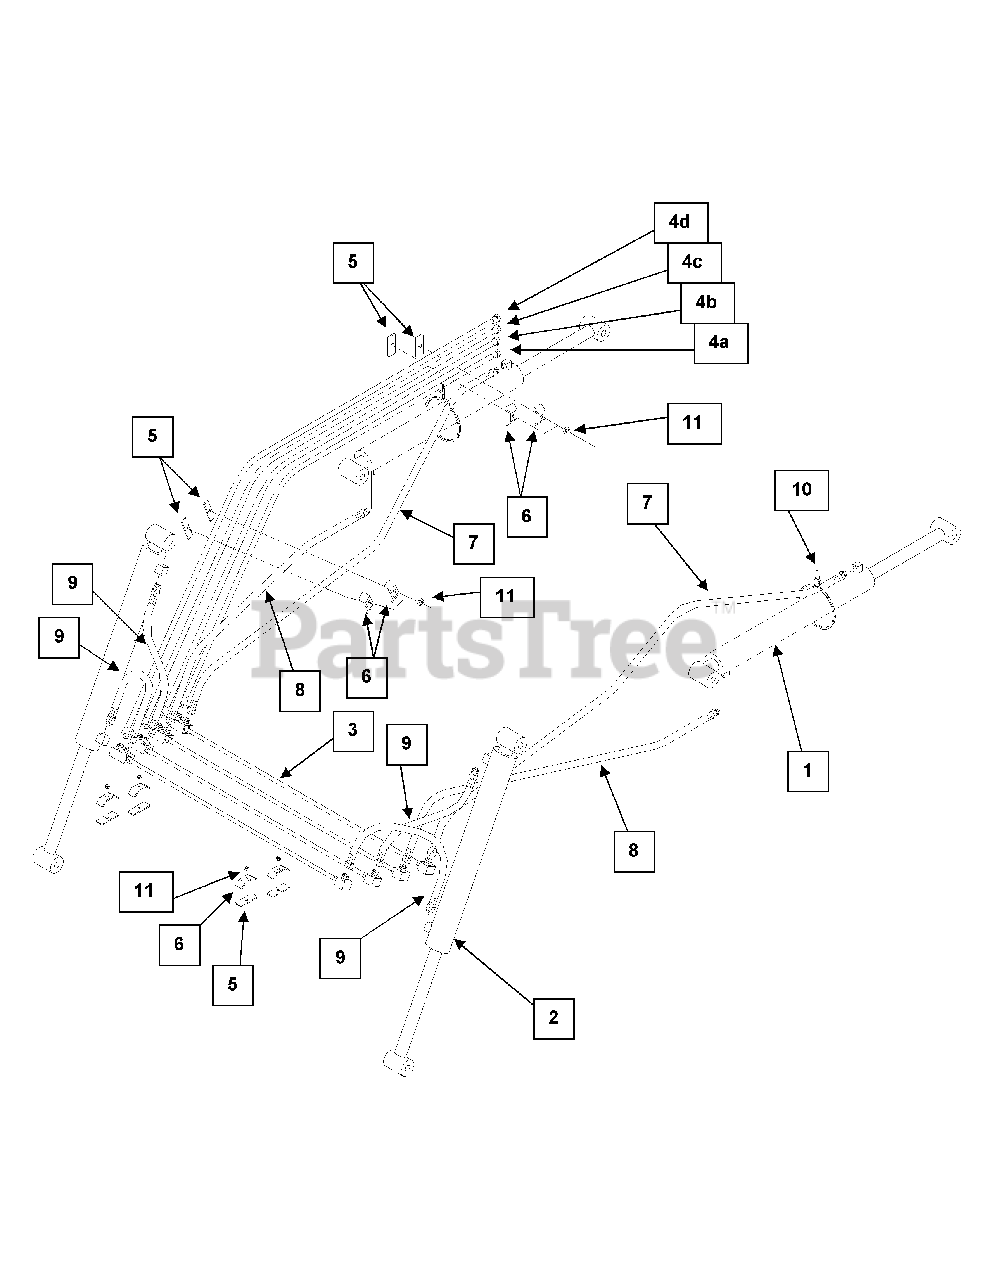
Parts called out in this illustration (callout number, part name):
1	Hydraulic Cylinder, Lift
2	Hydraulic Cylinder, Tilt, LH
2	Hydraulic Cylinder, Tilt, RH
3	Tubeline Assembly, Front
5	Tubeline Pad
6	Tubeline Clip
7	Hydraulic Hose Assembly, 3/8" x 48"
8	Hydraulic Hose Assembly, 3/8" x 28"
9	Hydraulic Hose Assembly, 3/8" x 18"
10	Plastic Tie Strap
11	Hex Head Nut, 5/16
